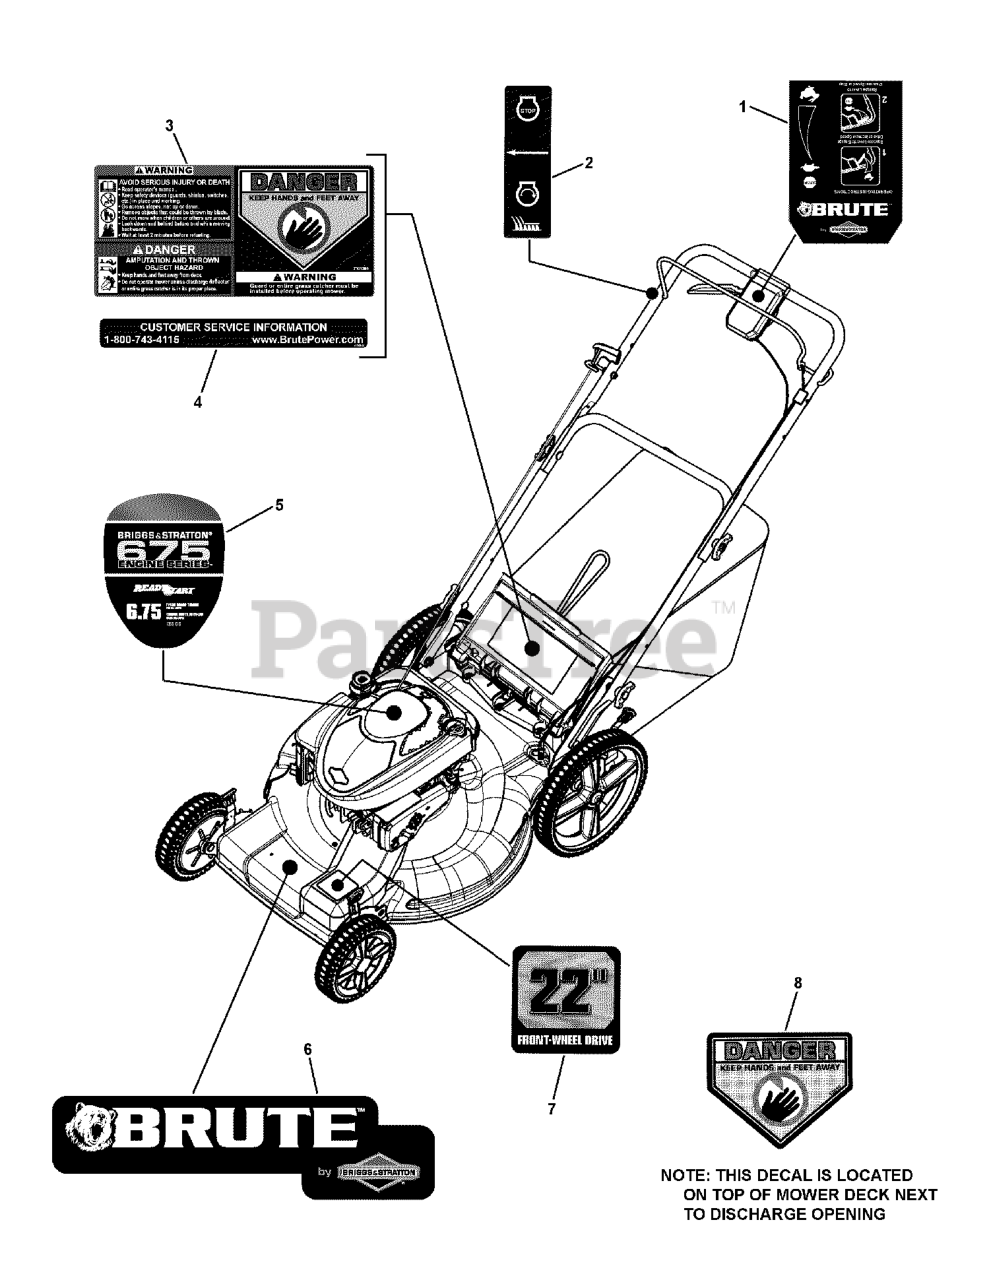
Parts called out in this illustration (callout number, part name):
1	DECAL, Control Head, 21" Brute
2	DECAL, OPC Bail International Symbol
3	DECAL, Warning, Rear Discharge Door
4	DECAL, Customer Service, Brute
5	DECAL, Engine 675, Brute
6	DECAL, Brute Walk-Behind Mower
7	DECAL, 22" Front Wheel Drive Brute
8	DECAL, Danger, Cut Finger
